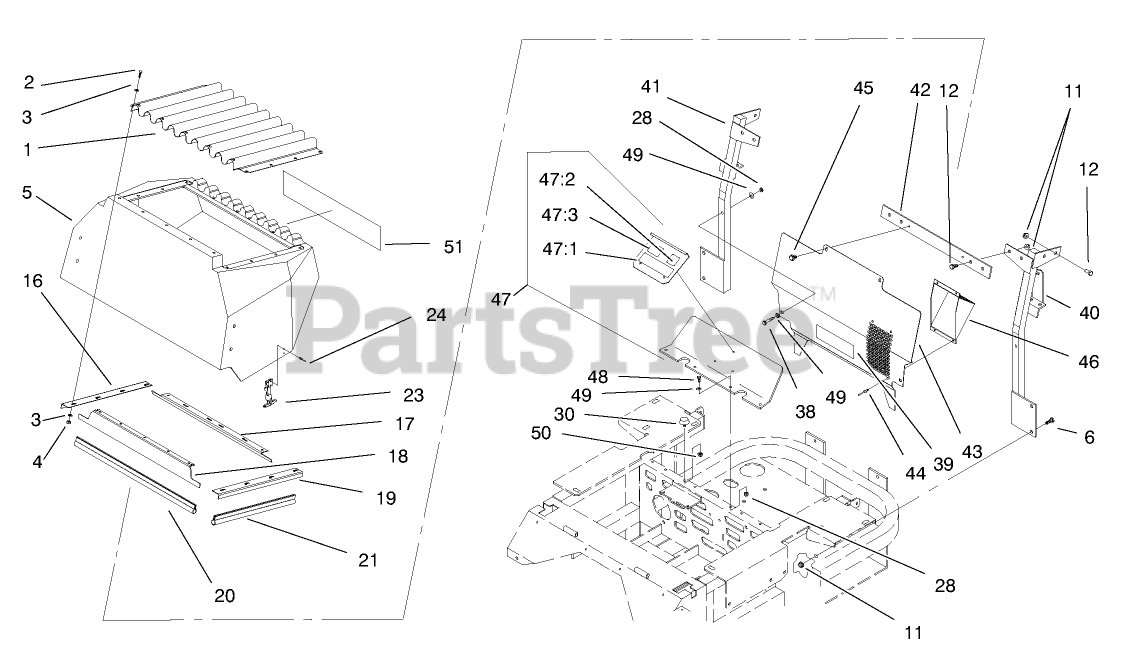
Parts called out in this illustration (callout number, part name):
1	Screen-Intake, Radiator
2	Screw-HSBH
3	WASHER-FLAT
4	Nut
5	Hood-Engine
6	SCREW-HH
11	NUT-HF
12	SCREW-HH
16	Angle-Trim, Radiator
17	Angle-Trim, Radiator
18	Angle-Trim, Radiator
19	Angle-Trim, Radiator
20	Seal-Trim
21	Seal-Trim
23	Latch-Rubber
24	Rivet
28	NUT-LOCK
30	Bumper
38	SCREW-HH
39	Decal-Belt Pump
40	Radiator Brace ASM, LH
41	Radiator Brace ASM, RH
42	Crossbar
43	Deflector-Air
44	Rivet-Pop
45	Screw-Tapping
46	Plenum-Intake, Air
47	Shield ASM
47:1	Decal-Belt, Drive
47:2	Decal-Guard
47:3	Decal-Important
48	SCREW-HH
49	Washer-Flat
50	NUT-HF
51	DECAL-Z MASTER LIQUID COOLED
